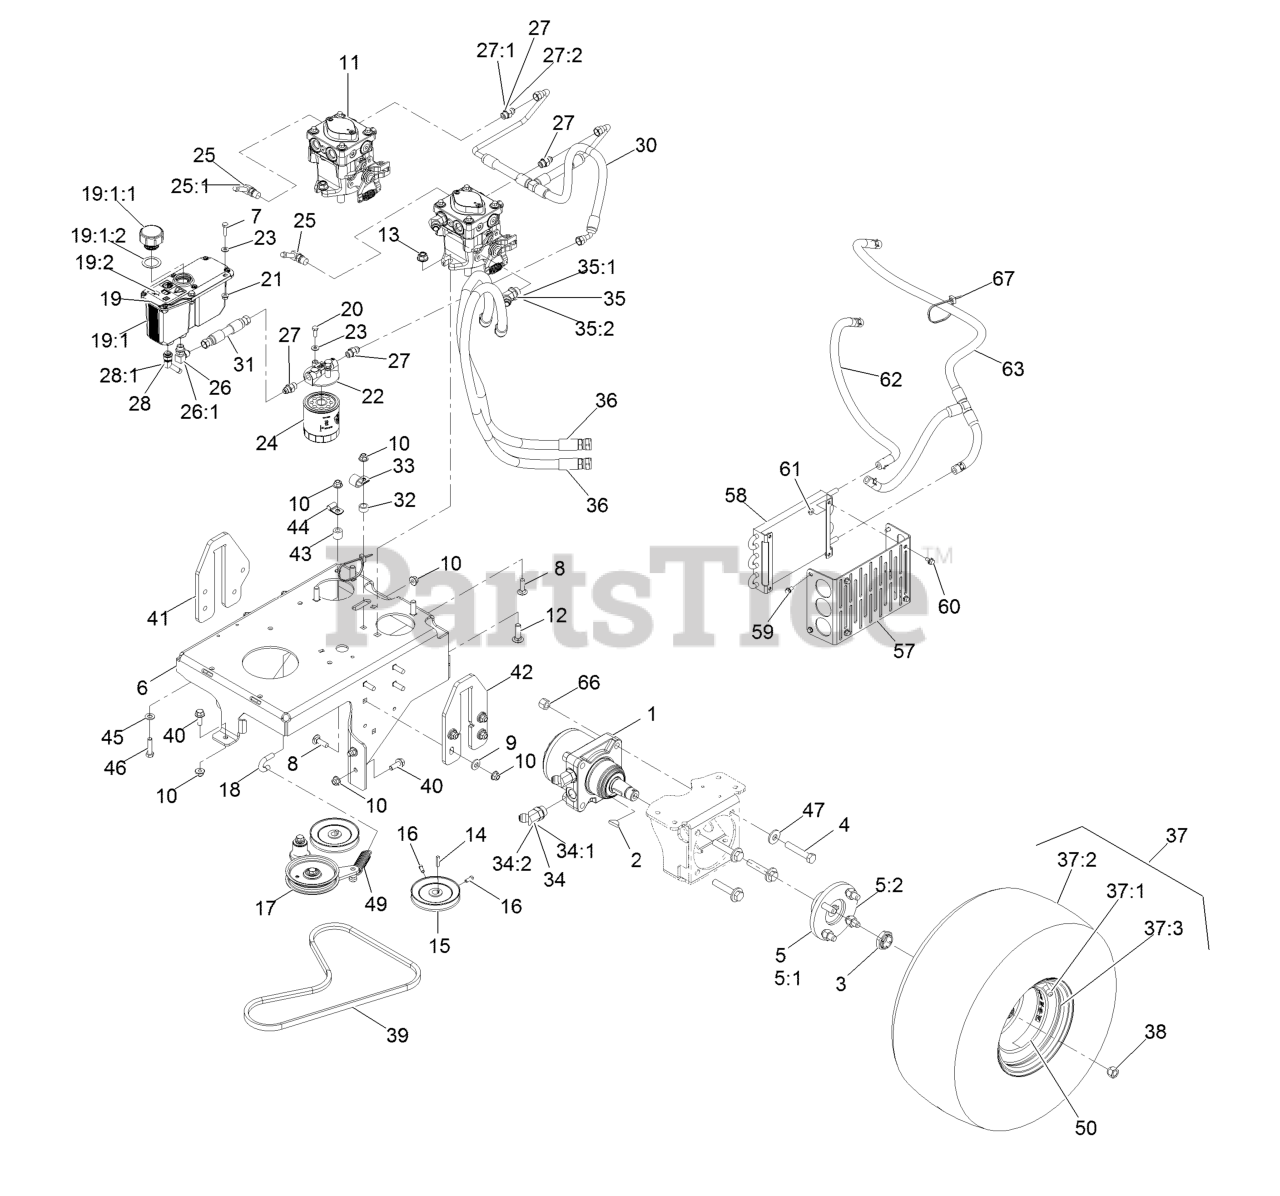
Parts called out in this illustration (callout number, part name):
1	Motor-Wheel
2	Key-Woodruff
3	Locknut
4	Screw-HH 1/2-13 X 2 3/4
5	Wheel Hub / Stud ASM
5:1	Hub-Wheel
5:2	Stud-Type, Drive
6	Base, Engine [red]
7	Screw-HH 1/4-20 X 1
8	Bolt-Carriage 3/8-16 X 1 1/4
9	Washer-Spring Disc 3/8
10	Nut-Nyloc 3/8-16 Flg
11	Pump - Hydraulic
12	Bolt-Carriage 7/16-14 X 1 1/2
13	Nut-HF, NI
14	Key-5Mm X 5Mm X 25Mm
15	Pulley-Pump
16	Setscrew-SQH 1/4-20 X 5/8
17	Pump Idler ASM
18	Anchor, Spring
19	Reservoir ASM
19:1	Reservoir-HYD
19:1:1	Cap-Reservoir, HYD
19:1:2	Gasket-Cap
19:2	Decal-Warning
20	Screw-HH 1/4-20 X 3/4
21	Nut-Hex 1/4-20 Side Lock
22	Filter-Head
23	Washer-1/4 SAE
24	Element, Oil Filter
25	Fitting-Elbow, 90
25:1	O-Ring
26	Fitting-Elbow, 90 DEG
26:1	O-Ring
27	Adapter-Straight
27:1	O-Ring-SAE #6
27:2	O-Ring-37 Flare #6
28	Fitting-Barbed, 45 DEG
28:1	O-Ring
30	Hose Assembly - Charge
31	HYD Hose ASM
32	Spacer-Wheel
33	Clip-Loom 5/8
34	Fitting-HYD, 45 DEG
34:1	O-Ring-SAE #10
34:2	O-Ring-37 Flare #8
35	Fitting-HYD, 45 DEG
35:1	O-Ring-SAE #8
35:2	O-Ring-37 Flare #8
36	HYD Hose ASM
37	Wheel/Tire ASM
37:1	Rim-8 Inch
37:3	Stem-Valve
38	Nut-Lug 1/2-20
39	Belt-V
40	Screw HHF 3/8-16 X 1
41	Plate-Lift, RH
42	Plate, Lift LH
44	Clip-Tube
45	Washer-3/8 SAE
46	Screw-HH 3/8-16 X 1 1/2
47	Washer-Spring Disc 1/2
49	Spring-Extension
50	Decal-Torque, Wheel Hub Lug
57	Bracket, Cooler Mounting
58	Cooler-Oil
59	Screw-HWH 1/4-20 X 1/2 Taptite
60	Screw-HHF
61	Nut-Keps
62	Hose-Hydraulic
63	Hose ASM-HYD LP 3/8
66	Nut-Nyloc 1/2-13
67	Tie-Cable
